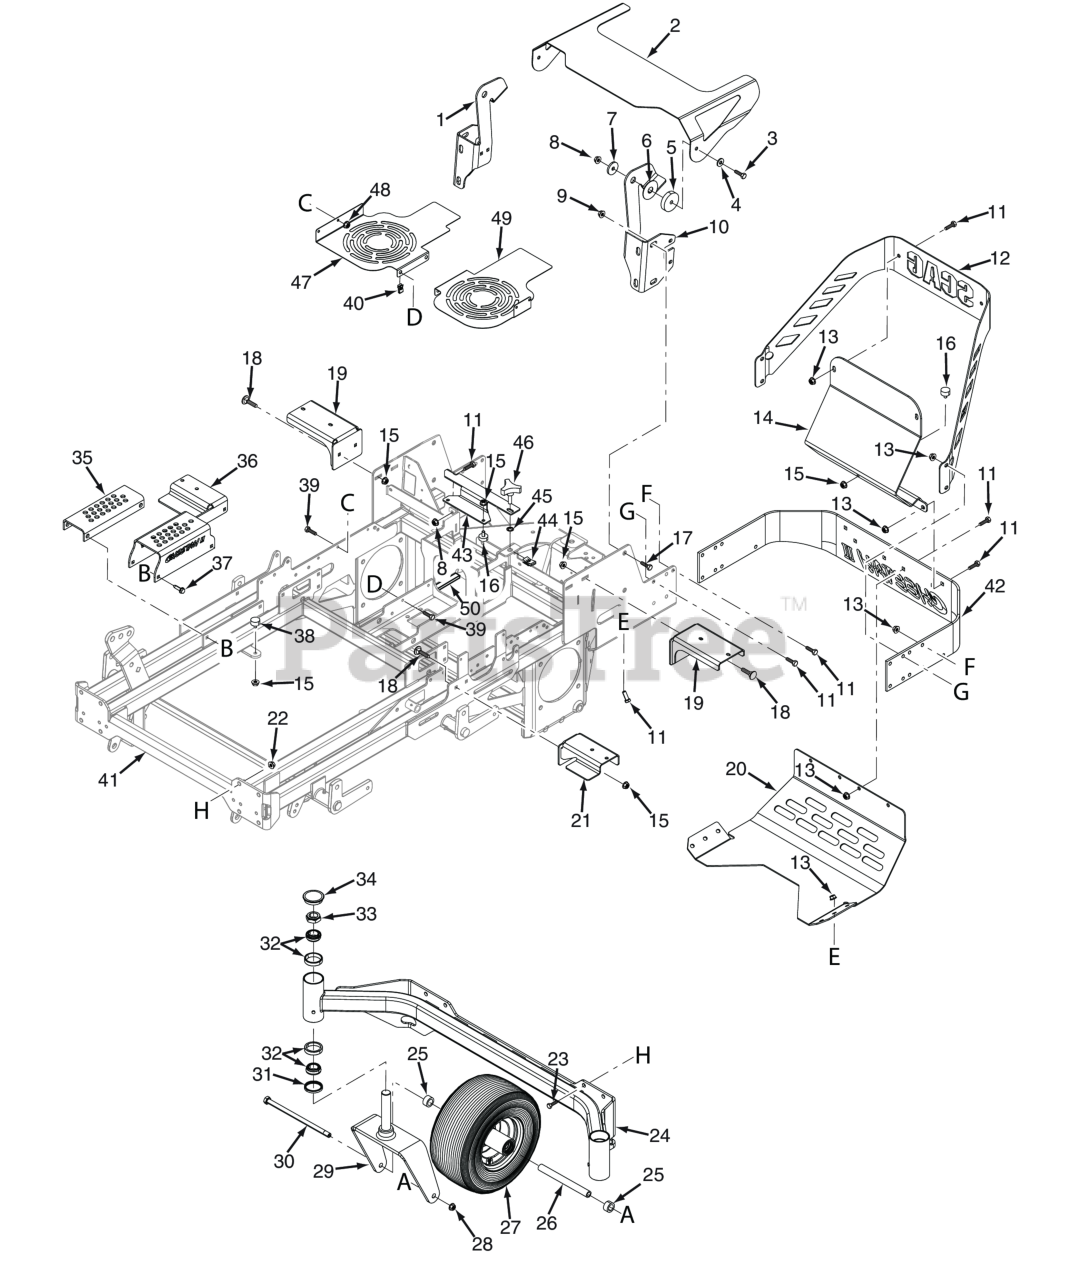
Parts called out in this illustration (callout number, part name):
1	ROPS Mount, RH, 29CV-EFI
2	Hood, SCZII
3	Bolt, Hex Head 3/8-16 x 1-3/4" (Kohler EFI)
4	Flatwasher, 3/8" Special (.391 x .938 x .105)
5	Spacer, Hood
6	Disc, Anti-Friction
7	Flatwasher, 3/8-.406 x 1-1-1/2 x 7 Gauge
8	HEX NUT, ELASTIC STOP LOCK, 3/8-16
9	Nut, Elastic Stop 1/2-13, (STT-52 & STTII-52)
10	ROPS Mount, LH, 29CV-EFI
11	Bolt, Hex Head, 3/8-16 x 1 Gr. 5
12	Engine Cover, Sides
13	NUT, 3/8-16 SERRATED FLANGE HEX HEAD
14	Engine Cover, Rear
15	Nut, Serrated Flange 5/16-18 (Right Front Engine Mounting, Briggs and Kohler Only)
16	Bumper, Rubber 5/16-18 x 5/8"
17	Bolt, Hex Head 1/2-13 x 1-1/4"
18	Bolt, 5/16-18 x .75 RHSN Carriage
19	Mounting Bracket, Fuel Tank Rear
20	Skid Plate, Rear
21	Mounting Bracket, Fuel Tank Front
22	Nut, 7/16-14 Flange Elastic Stop
23	BOLT, HEX HEAD, 7/16-14 X 1-1/4
24	Caster Support Weldment, 61V
25	Spacer, Caster Wheel
26	Sleeve, Caster Wheel (61V, 72A/VS)
27	Wheel Assy, 61V, 72V (Incl. 20, 54, 55)
28	HEX LOCKNUT, ELASTIC STOP, 1/2-13
29	Yoke Weldment
30	Bolt, Hex Head 1/2-13 x 9-1/2" (61V & 72A/VS)
31	Seal, 2.00" O.D. x 1.625" Bore
32	Bearing Set
33	Nut, Elastic Stop 1.0"-14
34	Cap, Grease
35	Adjustment Bracket, Lower Cut Height
36	Bracket, Upper Cutting Height
37	Bolt, Hex Wshr Head 5/16-18 x 1-1/4"
38	Bumper, Rubber
39	Bolt, Serrated Flange Hex Head 1/4 x 20 x 3/4"
40	Bolt, Hex Head 3/8-16 x 1"
41	Frame w/ Decals
42	Bumper, Rear
43	Cover, Battery Box
44	U-Nut, 3/8-16 (short)
45	Nut, Push-On - 3/8" Dia.
46	Knob, w/stud 3/8-16 x 1-1/4"
47	Fan Cover, RH
48	NUT, 1/4-20 SERRATED FLANGE HEX HEAD
49	Fan Cover, LH
50	PAD, BATTERY SUPPORT
